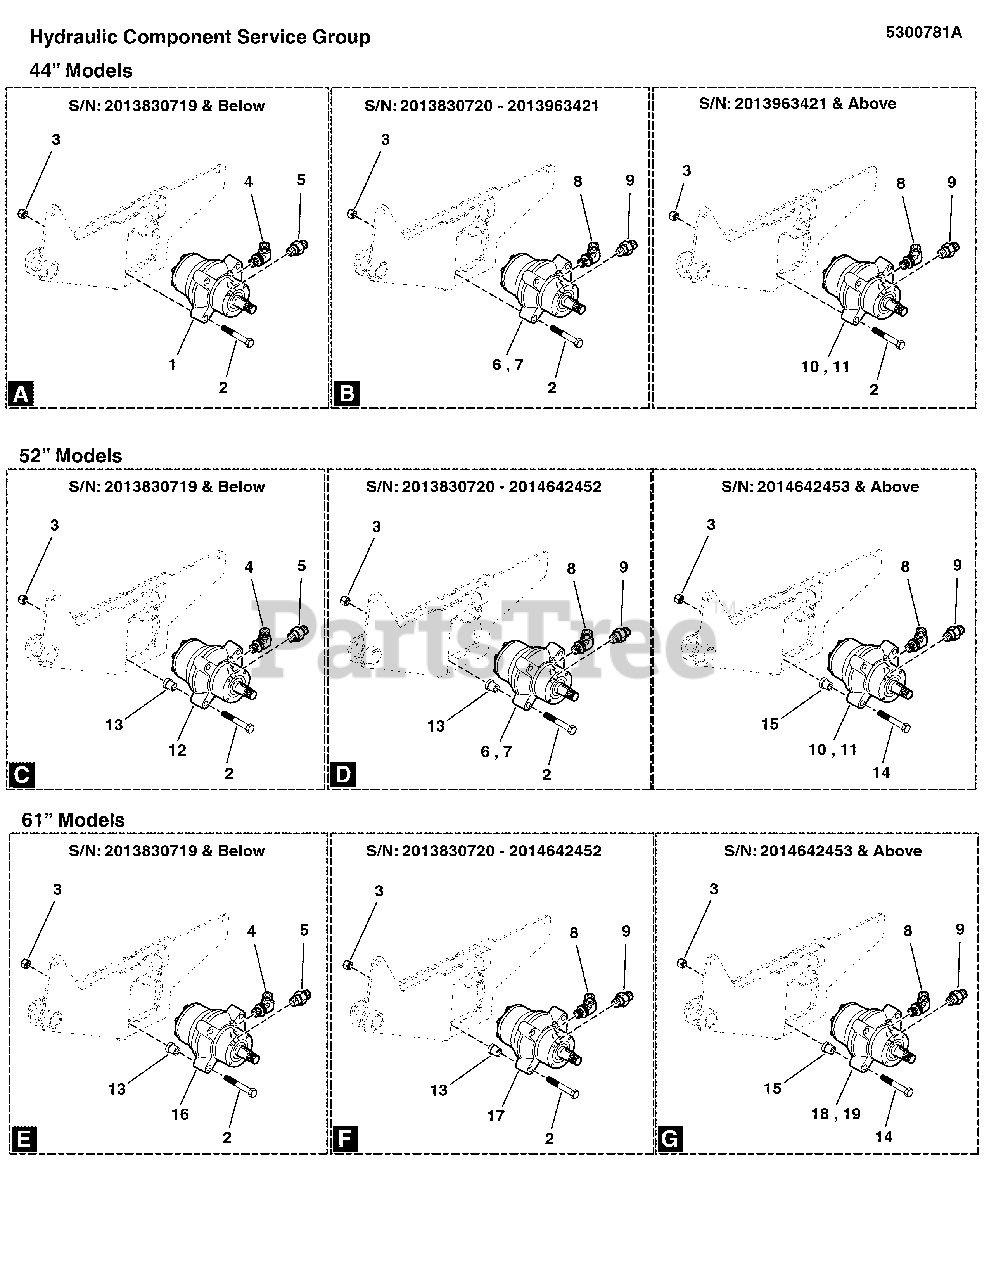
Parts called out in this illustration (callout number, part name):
2	BOLT, 1/2-13 X 2-1/4 PATCH
3	NUT, 1/2-13 SQUARE
4	FITTING, #8 JIC - #8 O-RING, 90 DEG.
5	FITTING, #8 O-RING X #8 JIC, STR
6	WHEEL MOTOR, HGM-12E-3054 (LH)
7	WHEEL MOTOR, HGM-12E-3050 (RH)
8	FITTING, #10 O-RING X #8 JIC, STR
9	FITTING, #10 ORING-#8 JIC, 90D
10	WHEEL MOTOR, LH, 11.9 CI SHORT
11	WHEEL MOTOR, RH, 11.9 CI SHORT
13	SPACER, .53 X 1.00 X 1.00, CZ
14	BOLT, 1/2-13 X 3.5, DRI-LOC PATCH
15	SPACER, .53 X 1.00 X 1.00, W/ FLAT, CZ
16	MOTOR, WHEEL, HGM-15C-4026
18	WHEEL MOTOR, LH, 14.5 CI-TF0240LS080AAKZ
19	WHEEL MOTOR, RH, 14.5 CI-TF0240LS081AAKZ
